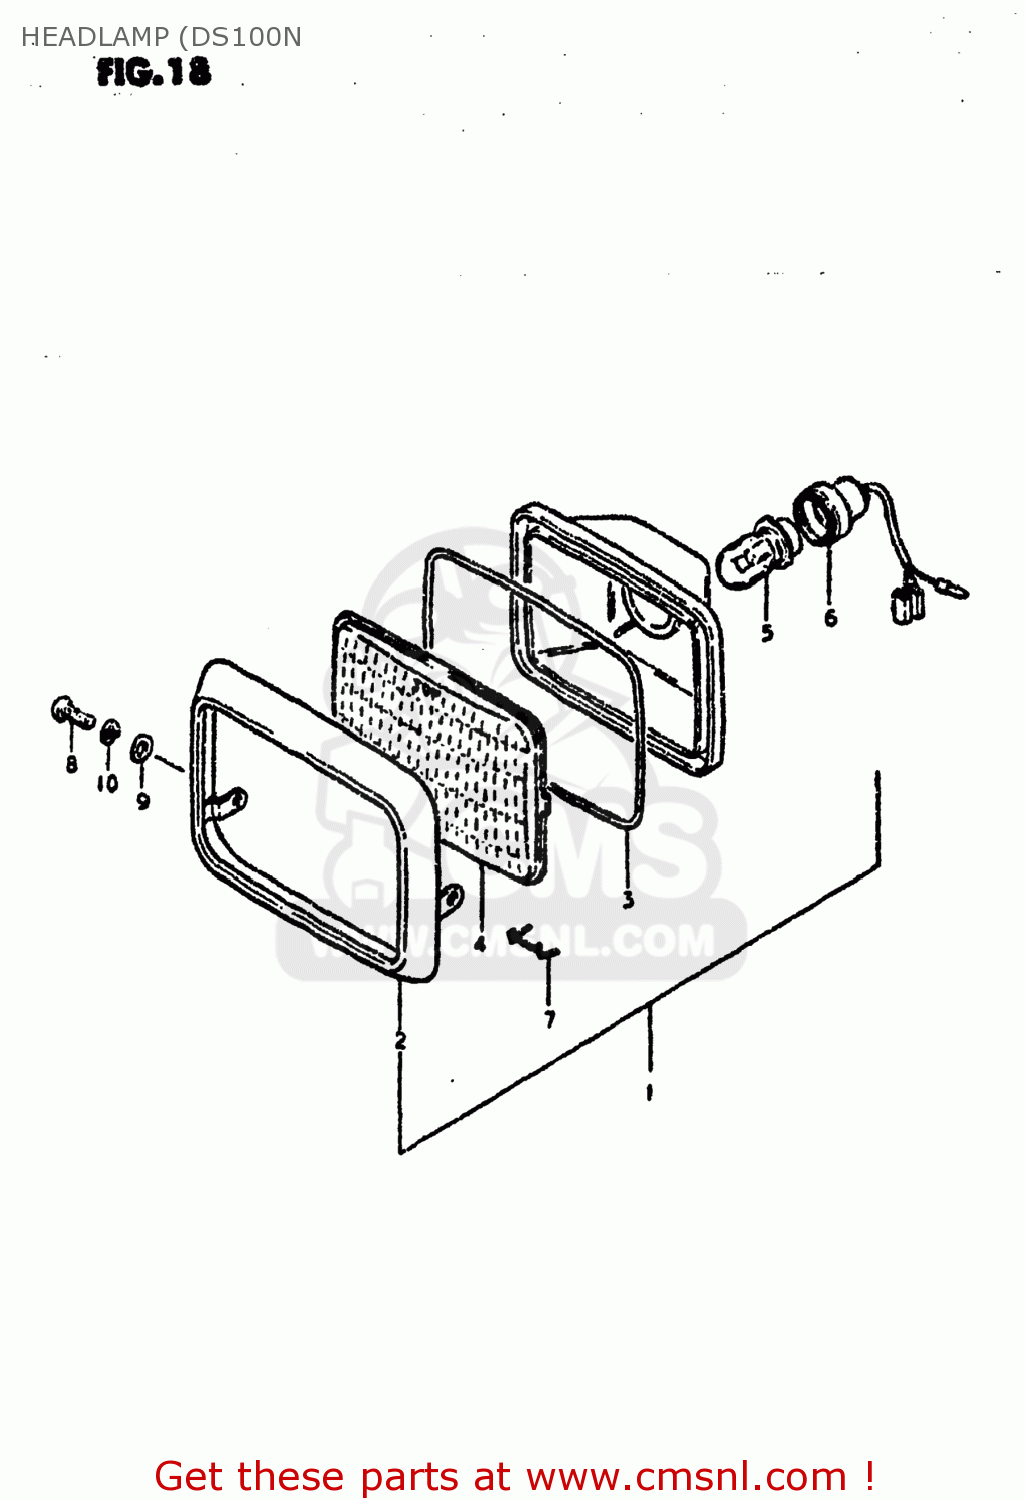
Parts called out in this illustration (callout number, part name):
1	LAMP ASSEMBLY,HEAD
2	RIM,HEADLAMP
3	GASKET,HEADLAMP LENS (NAS)
4	LENS,HEADLAMP (PLASTIC)
5	BULB(6V15/15W/STANLEY,A3598HA)
6	SOCKET,BULB
7	SPRING,HEADLAMP UNIT
8	SCREW
9	WASHER
10	LOCK WASHER
